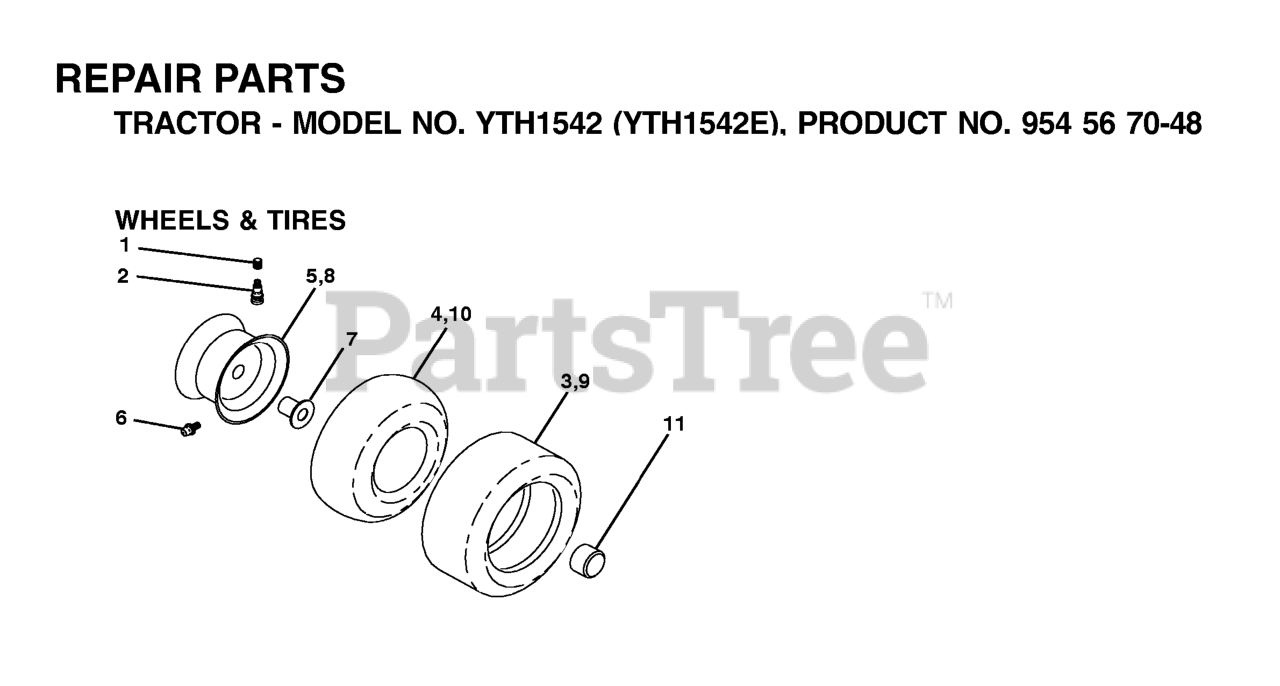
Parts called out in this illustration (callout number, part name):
2	VALVE STEM LT
3	TIRE HEAVY DUTY
4	TUBE.5.3/4.5/6
5	RIM ASM 6" FRONT SILVER
6	FITTING LT
7	BEARING T
8	RIM ASM 8" REAR SILVER
9	TIRE.TS.20X10-8
10	TUBE
11	CAP, AXLE BLK
